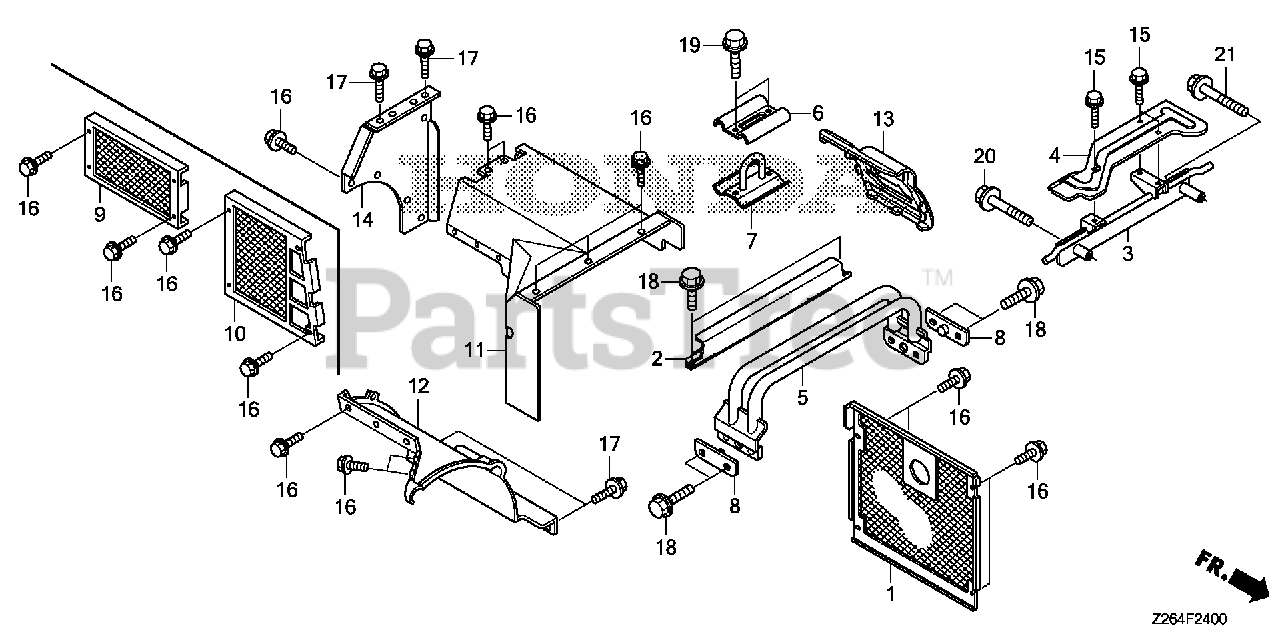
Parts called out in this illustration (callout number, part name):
1	PROTECTOR, MUFFLER *NH105* (MAT BLACK)
2	BRACKET, FUEL TANK *NH105* (MAT BLACK)
3	STAY, STOPPER
6	BRACKET, HANGER
7	HOOK, HANGER
8	PLATE, HANGER
9	PROTECTOR *NH105* (A) (MAT BLACK)
10	PROTECTOR *NH105* (B) (MAT BLACK)
11	DUCT, AIR (UPPER)
12	DUCT (LOWER)
13	SEAL, DUCT
15	BOLT, FLANGE (6X12) Use up to Engine SN 1543277.
16	BOLT, FLANGE (6X12)
17	BOLT, FLANGE (6X16)
18	BOLT, FLANGE (8X16)
19	BOLT, FLANGE (8X20)
20	BOLT, FLANGE (8X50)
21	BOLT, FLANGE (8X65)
